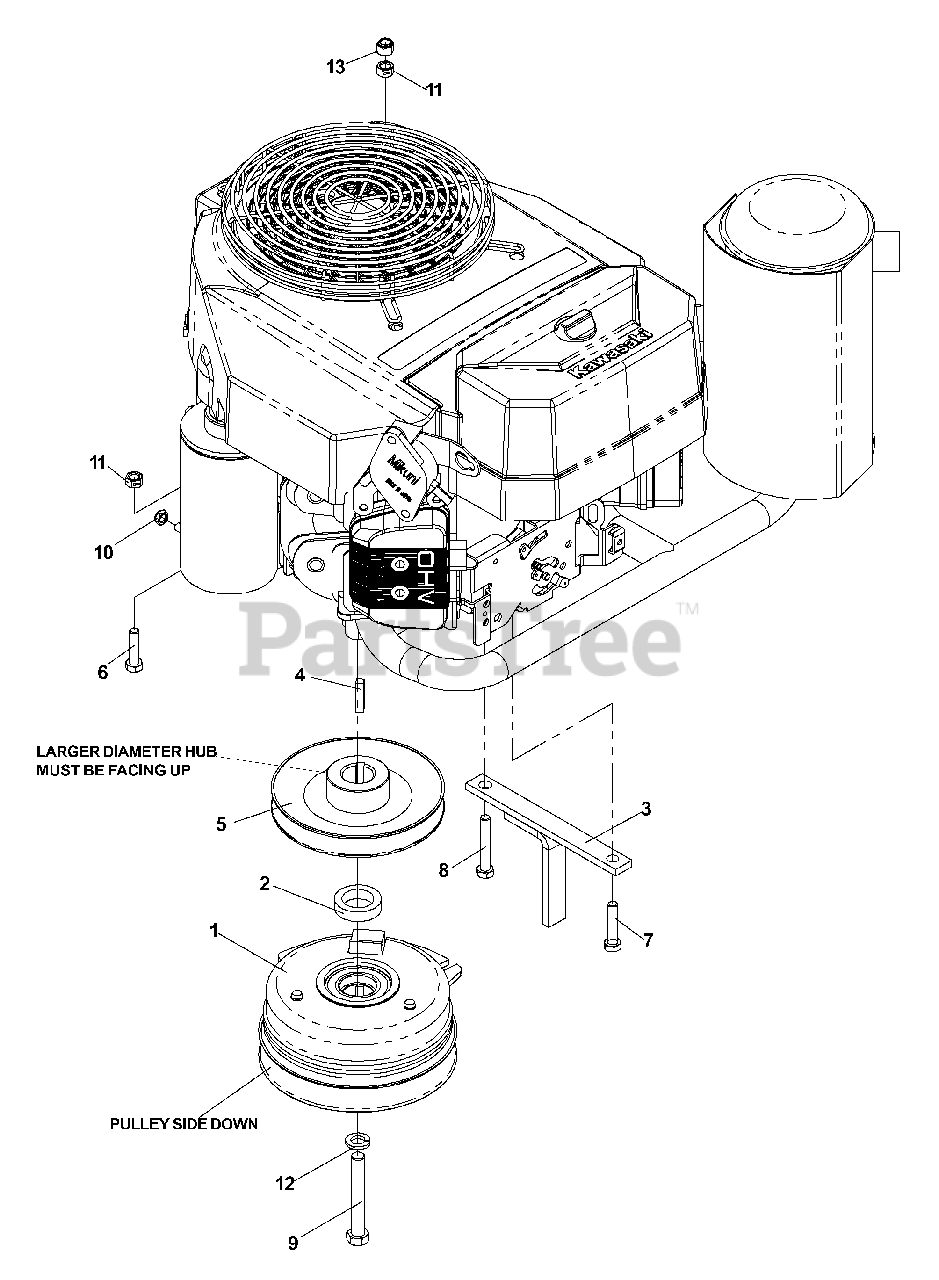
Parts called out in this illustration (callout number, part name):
1	CLUTCH, 125 FT/LBS
3	TIE DOWN, CLUTCH
4	KEY, 1/4" SQ. X 1 1/8"
5	PULLEY, PUMP
6	HCS, 5/16-18 X 1 1/4
7	HCS, 5/16-18 X 1 1/2
8	HCS, 5/16-18 X 2
9	HCS, 7/16-20 X 3
10	NUT, 1/4C, THIN NYLOC
11	NUT, 5/16C, CENTER LOCK
12	LOCKWASHER, 7/16
13	NUT, 5/16, NYLOC
